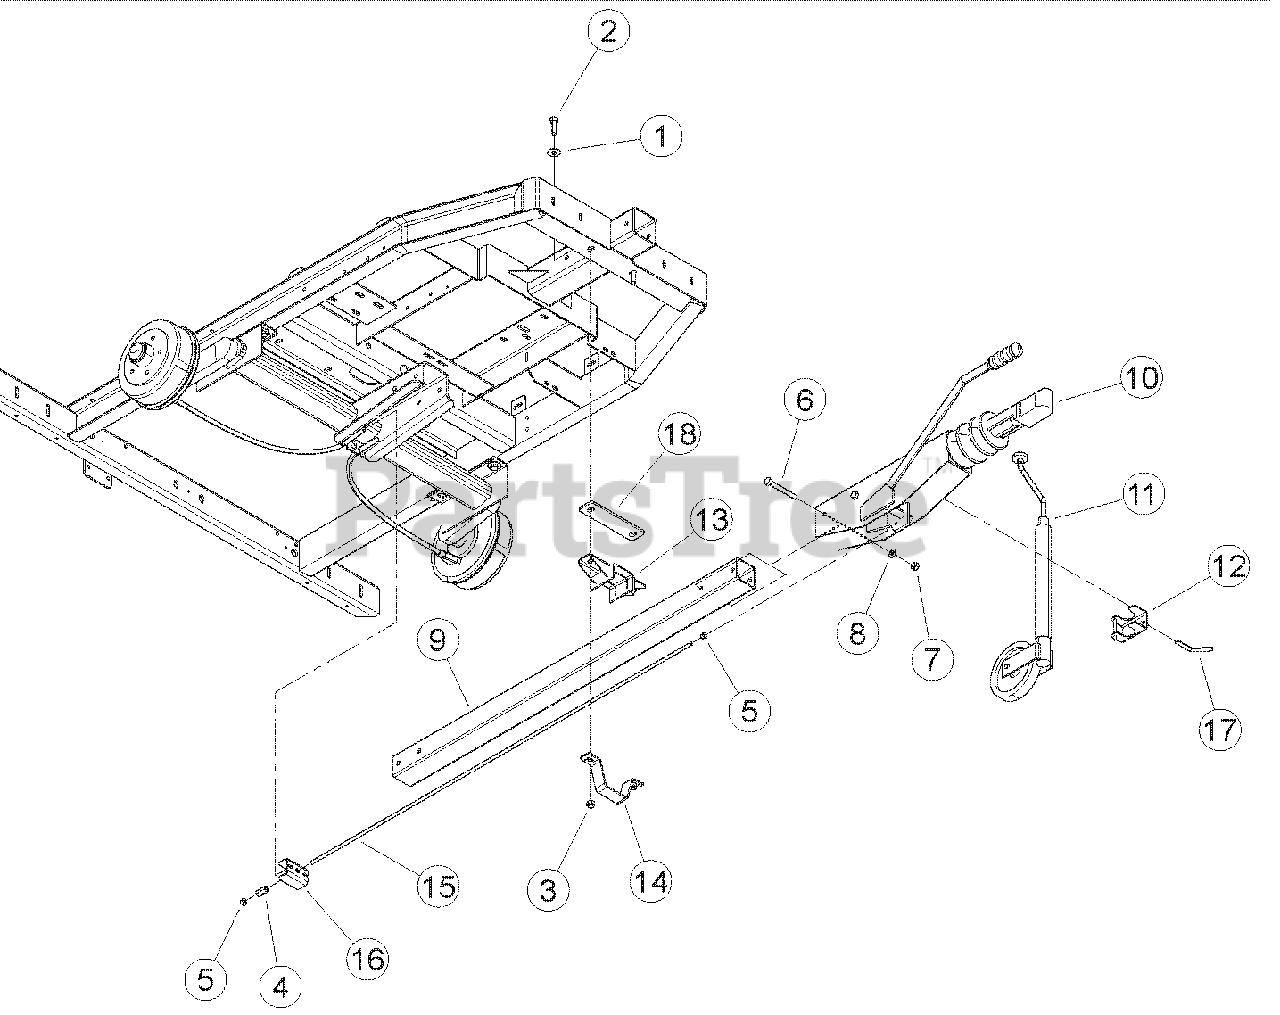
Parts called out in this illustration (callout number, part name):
1	WASHER, 1/2 FLAT ZP
2	BOLT, M12 X 1.75 X 40 HEX HD GR8.8
3	NUT, M12 X 1.75 HEX NYLOCK TYPE NEYZP
4	NUT, SPHERICAL M10 X 35MM
5	NUT, M10 HEX
6	BOLT, M12 X 100 CLASS 10.9
7	NUT, M12 HEX
8	WASHER, M12 FLAT
9	DRAWBAR, 70MM X 70MM
10	COUPLER, 50MM W/ BRAKE HANDLE
11	JACK, JOCKEY WHEEL
12	CLAMP, JOCKEY WHEEL
13	MOUNT, FRONT DRAWBAR
14	CLAMP, FRONT DRAWBAR
15	ROD, BRAKE CONTROL
16	BRACKET, BALANCE BAR
17	HANDLE, JOCKEY WHEEL CLAMP
18	PLATE, DRAWBAR MOUNT
